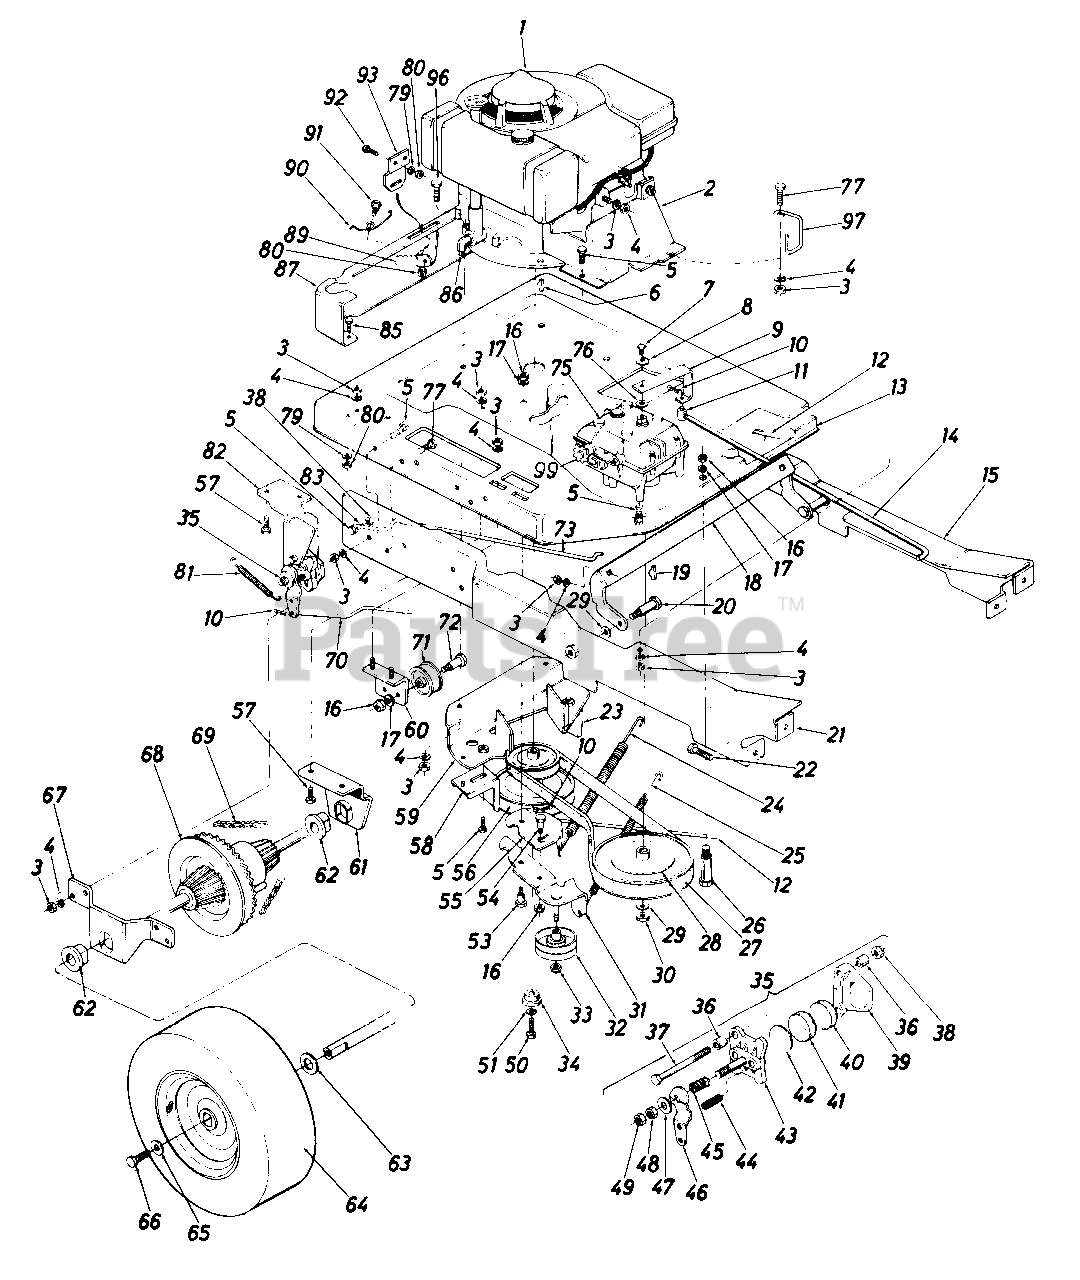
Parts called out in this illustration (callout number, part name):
1	Engine
2	Hot Air Duct
3	Hex Nut 5/16-18 Thd.
4	L-Wash. 5/16 Scr.
5	Hex Sems Scr. 5/16-18 x .75
6	#6 Hi-Pro Key 5/32 x 5/8 Dia.
7	Hex Scr. 5/16-24 x .50 Lg.
8	Belleville Wash. .345 I.D.
9	Shift Brkt.
10	Cotterpin 3/32 x .75
11	Adjustment Ferrule
12	Clutch Rod
13	Engine Mtg. Plate
14	Shift Rod
15	Slide Rail L.H.
16	Hex Cent. L-Nut 3/8-16 Thd.
17	Spring L-Wash. 3/8 Scr.
19	#4 Hi-Pro Key 3/32 x 5/8" Dia.
20	Shld. Scr. .625 Dia. x 1.5" Lg.
21	Side Rail Ass'y. R.H.
22	Hex Scr. 3/8-16 x .75 Lg.
23	Belt Keeper
24	Ext. Spring
25	Tension Spring
26	Shld. Scr. .62 x 1.75
27	V-Belt 1/2 x 48
28	Transmission Pulley
29	Spring L-Wash. 1/2 Scr.
30	Hex Jam Nut 1/4-20
31	Idler Brkt. Ass'y.
32	Flat Idler
33	Hex Ins. L-Nut 3/8-24
34	Step Washer
35	Brake Ass'y. - Comp.
36	Bushing .442 Dia. x .375 Lg.
37	Hex Scr. 5/16-18 x 2.25 Lg.
38	Hex Cent. L-Nut 5/16-18 Thd.
39	Casting Carrier
40	Friction Pad 1.110 Dia. x .245 Thick
41	Friction Pad 1.110 Dia. x .430 Thick
42	Back Up Washer
43	Casting Cam
47	Washer
48	Hex Top L-Nut
49	Hex Centerlock Nut
50	Hex Scr. 3/8-24 x 1.75 Lg. H.T.
51	Spring L-Wash. 3/8 Scr.
53	Shld. Scr. .500 Dia. x .340
54	Shld. Scr. .500 Dia. x .170
55	Idle Pivot Brkt.
56	Two Step Engine Pulley
58	Belt Keeper
59	Belt Guard Ass'y.
60	Chain Idler Ass'y.
61	Bearing Support
62	Flange Bearing - Plastic
63	Flat Washer .812 I.D.
64	Rear Wheel Ass'y. - Comp.
65	Belleville Washer
66	Hex Scr. w/Lock 5/16-24 x .75 Lg.
67	Bearing Brkt.
68	Differential Ass'y. - Comp.
69	#420 Chain 1/2 x 71 Links
70	Brake Rod
71	Flat Idler
72	Shld. Scr. .500 x .48 Lg.
73	Rear Cover Prop
75	Transmission 4 Speed - Peerless
76	Hardened Washer
77	Hex Sems Scr. 5/16-18 x 1 Lg.
79	L-Wash. 1/4 Scr.
80	Hex Nut 1/4-20 Thd.
81	Brake Return Spring
82	Brake Hanger Brkt.
83	Flat Wash. .344 I.D.
85	Hex Scr. 1/4-20 x .50 Thd.
86	90° Elbow Male to Female 3/8" Thd.
87	Rear Panel
89	Hook Brkt.
91	Shld. Scr.
92	Carr. Bolt 1/4-20 Thd.
93	Latch Brkt.
96	Hex Scr. 5/16-18 x 1 1/2 Lg.
97	Belt Guide
